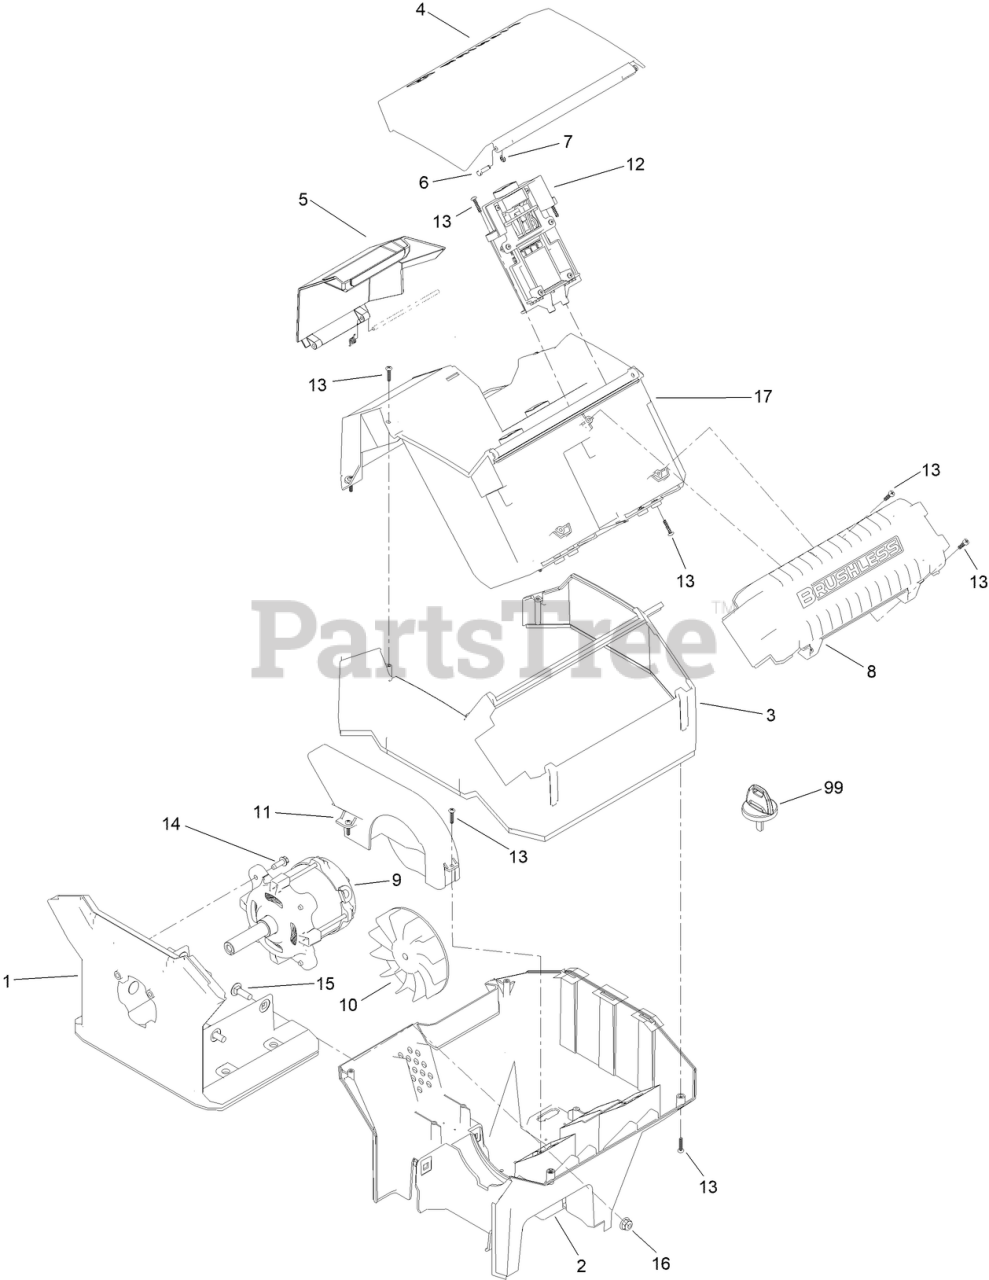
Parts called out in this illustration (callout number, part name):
1	MOTOR MOUNT
2	HOUSING-MOTOR
3	COVER-CONTROLLER
4	DOOR-TOP
5	DOOR-BOTTOM
6	PIN-BATTERY COVER
7	RING-RETAINING
8	MOTOR CONTROLLER ASM-POWERHEAD
9	MOTOR-60V, 2 STAGE
10	FAN-FC
11	COVER-FAN
12	BATTERY TRACK ASSEMBLY
13	SCREW-PPH
14	SCREW-HWHTF
15	BOLT-CARR
16	NUT-HF, NI
17	BUCKET-BATTERY
99	KEY-60V 2 STAGE POWER HEAD
